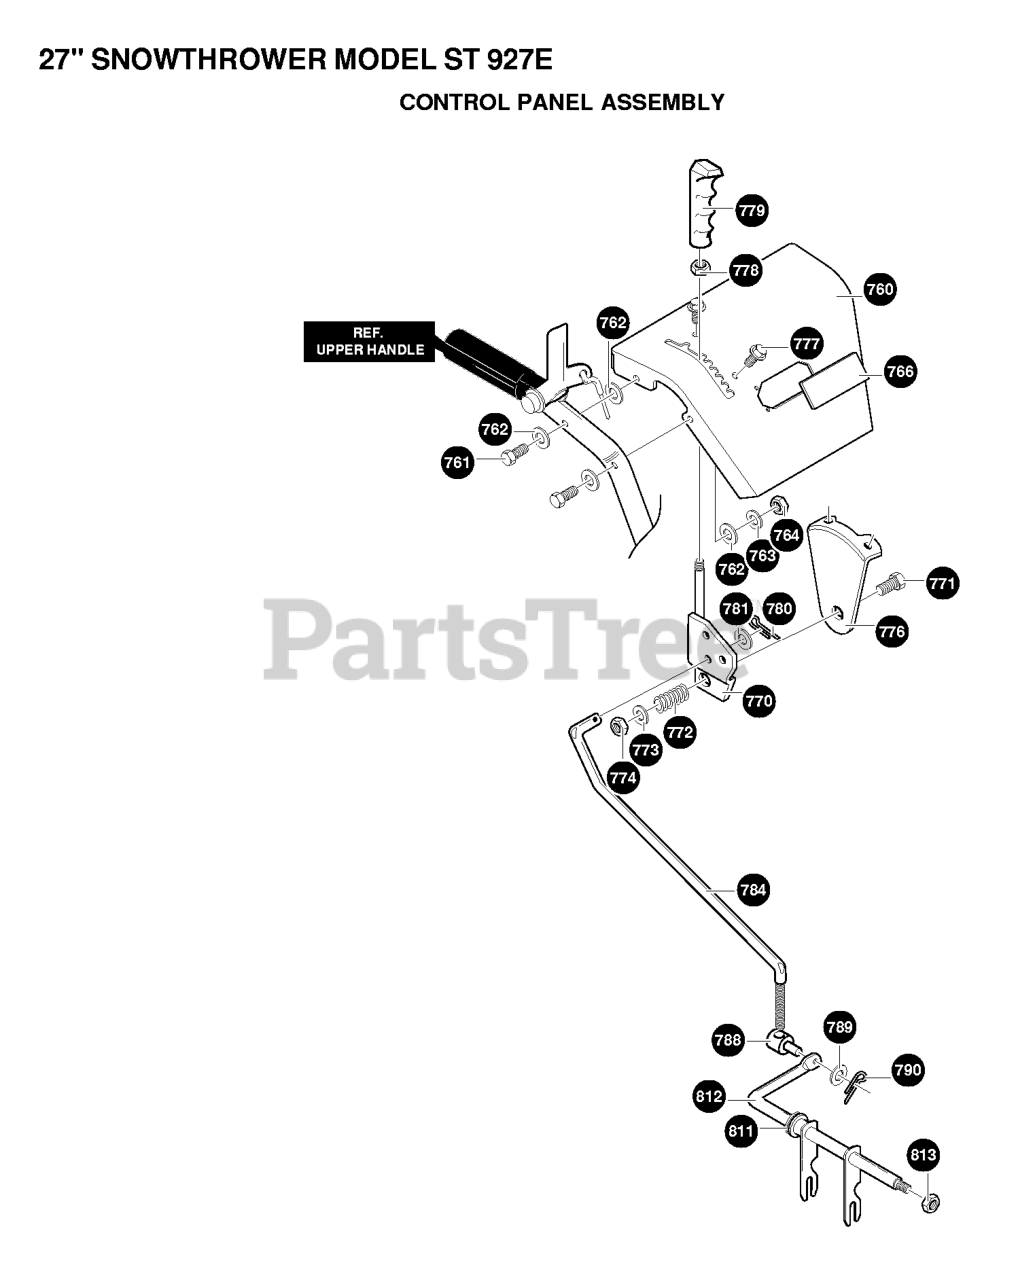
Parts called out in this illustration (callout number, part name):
760	PANEL, CONTROL W/LIGHT
762	WASHER, FLAT .344X .69X.
763	WASHER, HVSPTLK .328X.60X
764	NUT, 5/16-18 REGHEX
766	PLATE, PANEL
770	SPEED CONTROL HANDLE
773	WASHER, FLAT .406X .81X.
774	NUT, 3/8-16 HEXNYL
777	SCREW, 5/16-18X .50 WAHHT
778	NUT, 3/8-16 REGHXCTRLK
779	HANDLE, 3/8-16 MOLDED GRE
780	PIN, COTTER .090/.086X.75
781	WASHER, FLAT .344X .69X.
789	WASHER, FLAT .344X .69X.
790	PIN, COTTER .090/.086X.75
811	FLANGE BEARING
812	ROD, ASSY YOKE
813	NUT, 3/8-16 REGHXCTRLK
